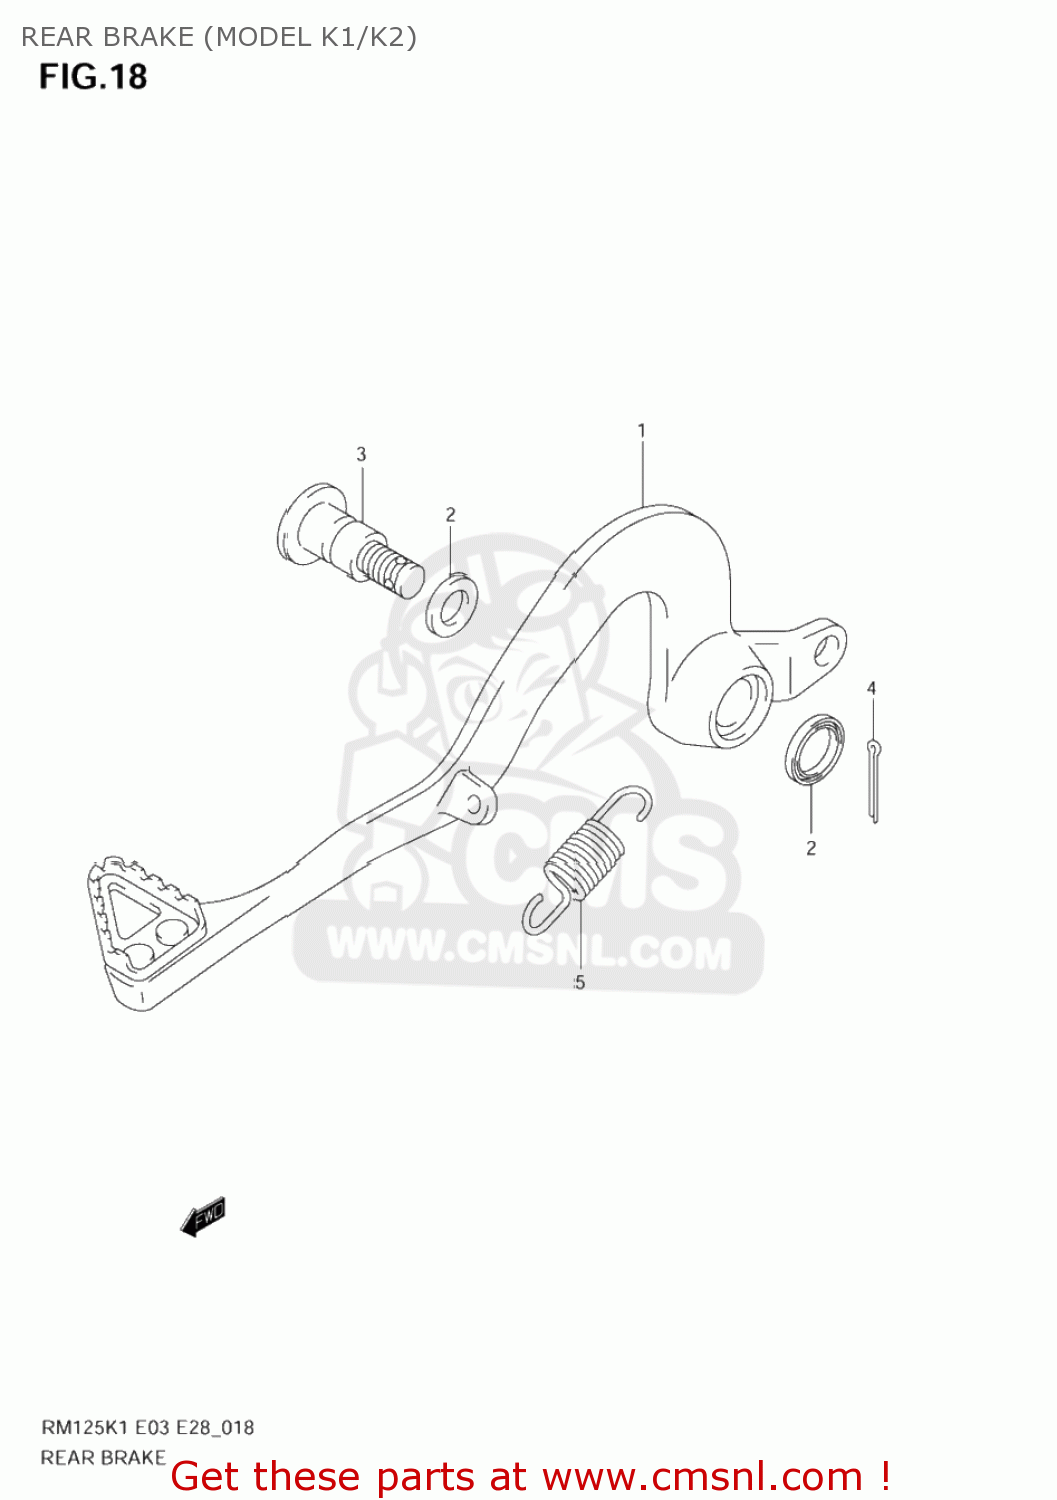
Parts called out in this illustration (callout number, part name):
1	PEDAL ASSY,BRAKE
2	SEAL,OIL(15X21X3)
3	SHAFT,BRAKE PEDAL
4	PIN 20X20
5	SPRING
